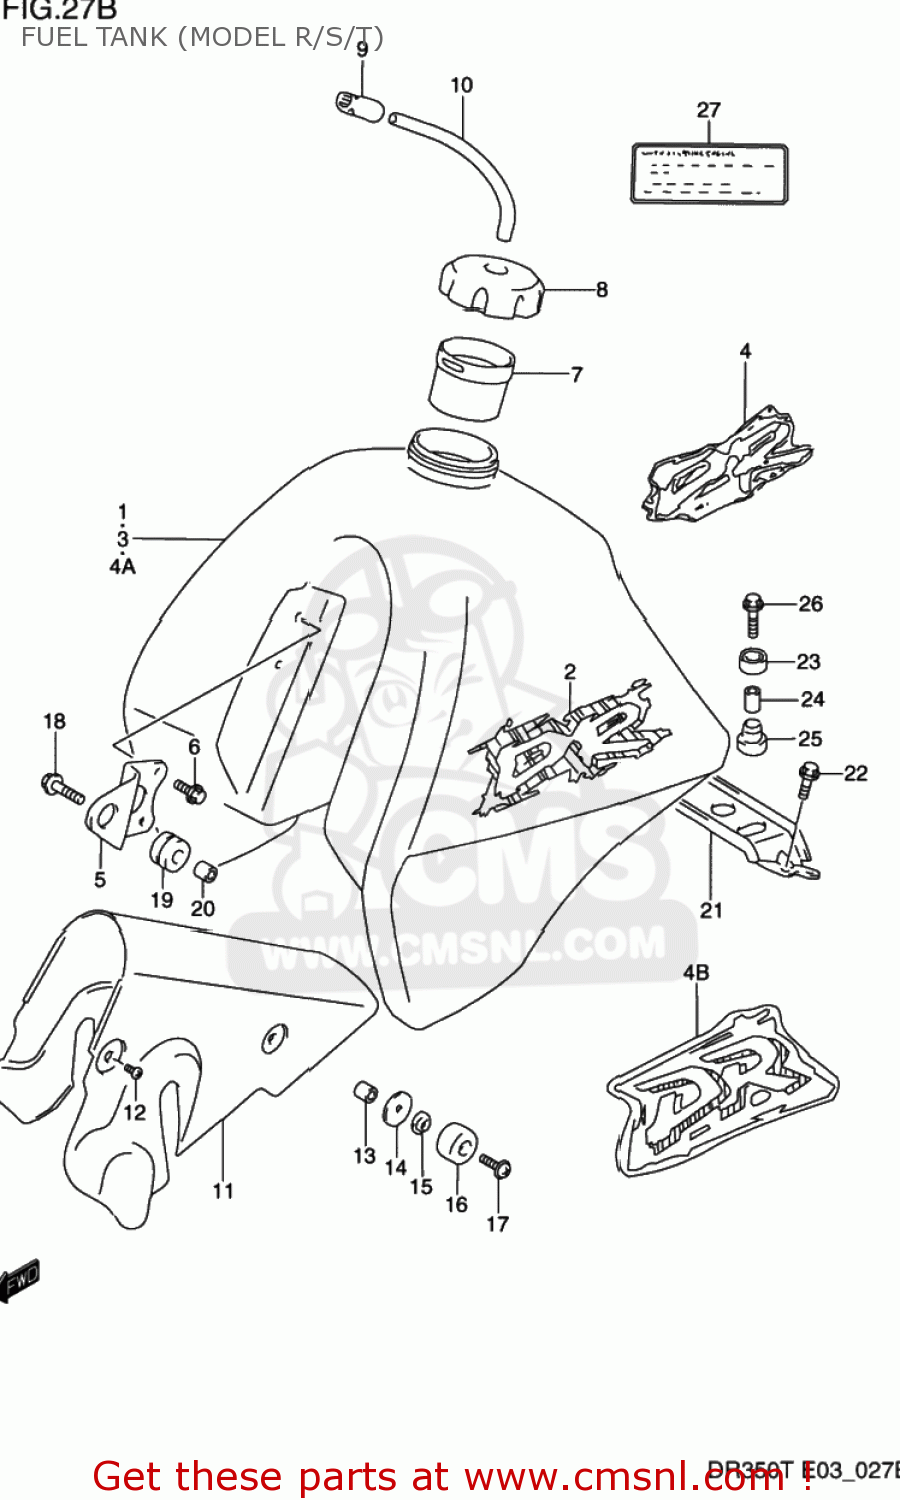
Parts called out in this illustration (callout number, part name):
1	TANK ASSY,FUEL(WHITE)
2	EMBLEM SET,FUEL TANK
3	TANK ASSEMBLY,FUEL
4	EMBLEM SET,FUEL TANK
4A	TANK ASSEMBLY,FUEL
4B	TAPE SET,FUEL TANK
5	BRACKET,FUEL TANK,FRONT
6	BOLT
7	TUBE,FILLER INLET
8	CAP ASSY,FUEL TANK
9	CLAMP,FUEL TANK BREATHER HOSE
10	HOSE(5X8.2X600)
11	HEAT SHIELD,FUEL TANK
12	BOLT
13	SPACER(6.1X14X7.2)
14	WASHER (6.5X26X2.3)
15	WASHER
16	CUSHION
17	SCREW
18	BOLT(8X25)
19	CUSHION
20	SPACER (8.8X12X12.5)
21	BRACKET,FUEL TANK RR
22	BOLT
23	CUSHION
24	SPACER
25	CUSHION
26	BOLT
27	LABEL,STARTING CAUTION
